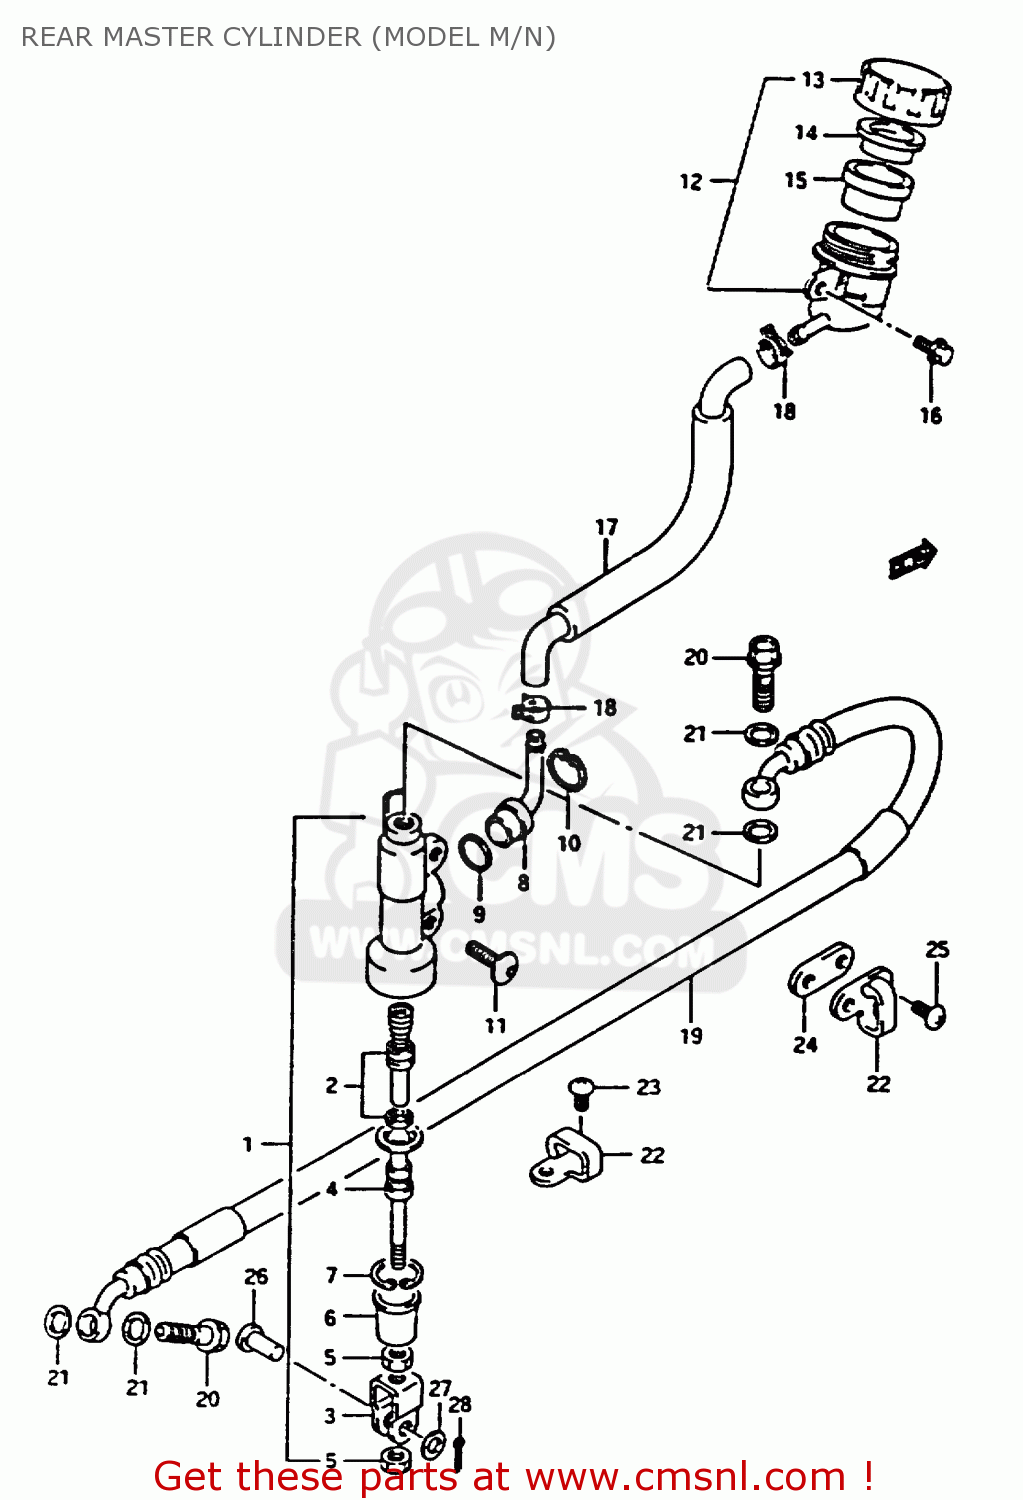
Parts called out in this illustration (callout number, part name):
1	CYLINDER ASSY,RR MASTER
2	PISTON/CUP SET
3	YOKE
4	ROD,PUSH
5	NUT
6	BOOT
7	CIRCLIP
8	CONNECTOR
9	O RING
10	CIRCLIP
11	SCREW(6X16)
12	TANK ASSY,RR BRAKE RESERVOIR
13	CAP
14	PLATE
15	DIAPHRAGM
16	BOLT
17	HOSE,TANK
18	CLAMP,RESERVOIR HOSE
19	HOSE,REAR BRAKE
20	BOLT UNION
21	WASHER(10X15X1.5)
22	GUIDE,RR BRAKE HOSE
23	SCREW(5X10)
24	SEAT,RR BRAKE HOSE GUIDE
25	SCREW
26	PIN(8X20)
27	WASHER(8.5X13X1.6)
28	PIN
